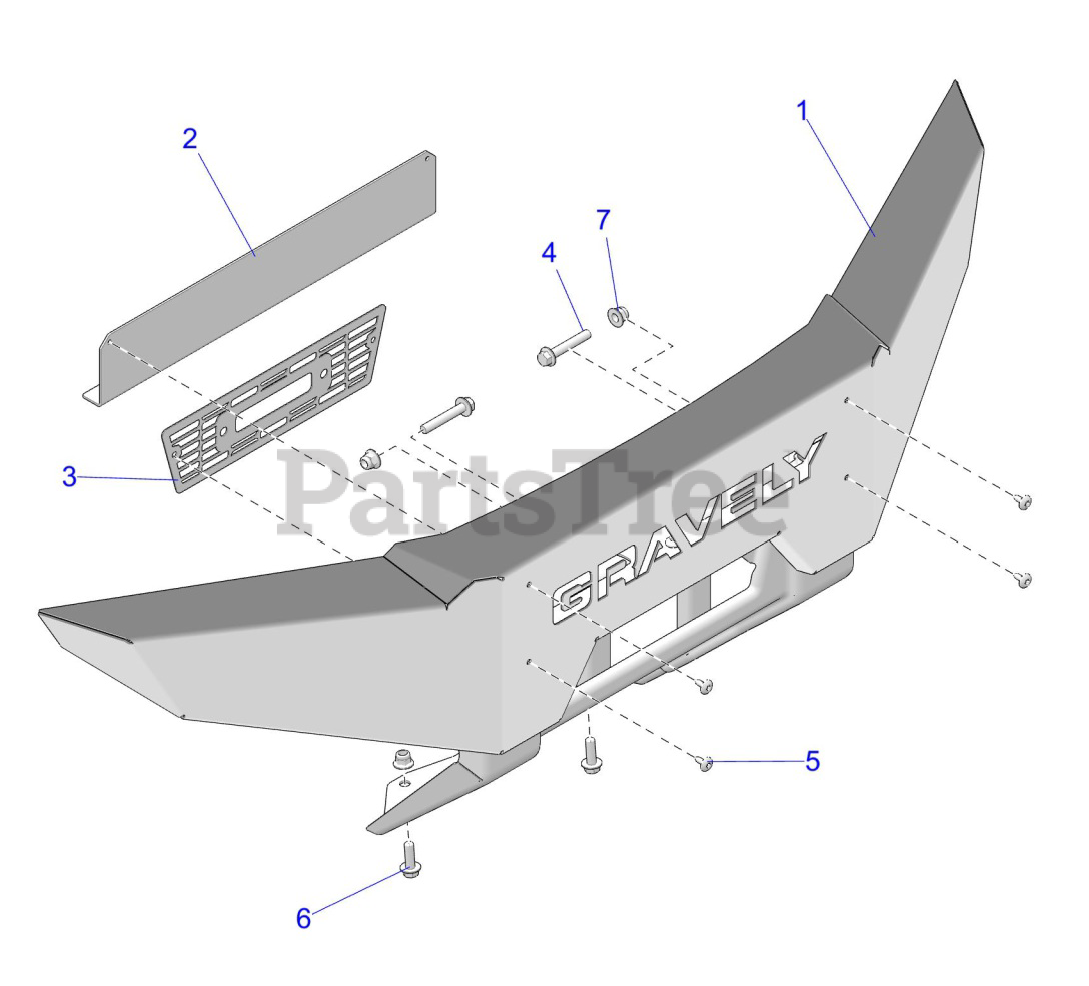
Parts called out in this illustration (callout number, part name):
1	WELD-BUMPER,FRONT,ARIENS,M BLK
2	PLATE, GRAVELY RED
3	SCREEN-BUMPER,BLK
4	BOLT-M10X1.25X60,HXFLG-OLIVE D
5	SCR-M6X1X16 TR/TX-M
6	SCR-HXFL-M10X1.25X30 8.8 ZOD
7	NUT-M10X1.25,FLG,NYLOC-OLIVE D
